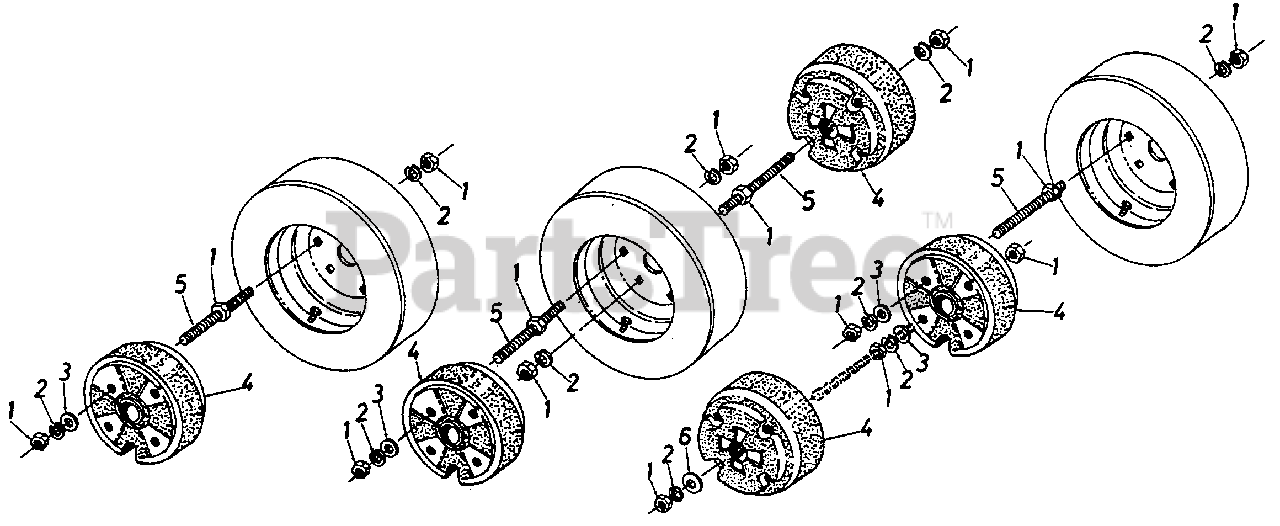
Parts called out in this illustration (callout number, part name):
1	Hex Nut 1/2-13 Thd.
2	Lock Wash. 1/2" I.D.
3	Flo-Wash. .53" I.D. x .93" O.D.
4	Wheel Weight
5	Rod Threaded 1/2-13 x 9.5" Lg.
6	Fl-Wash. .5" I.D. x 2.0" O.D.
